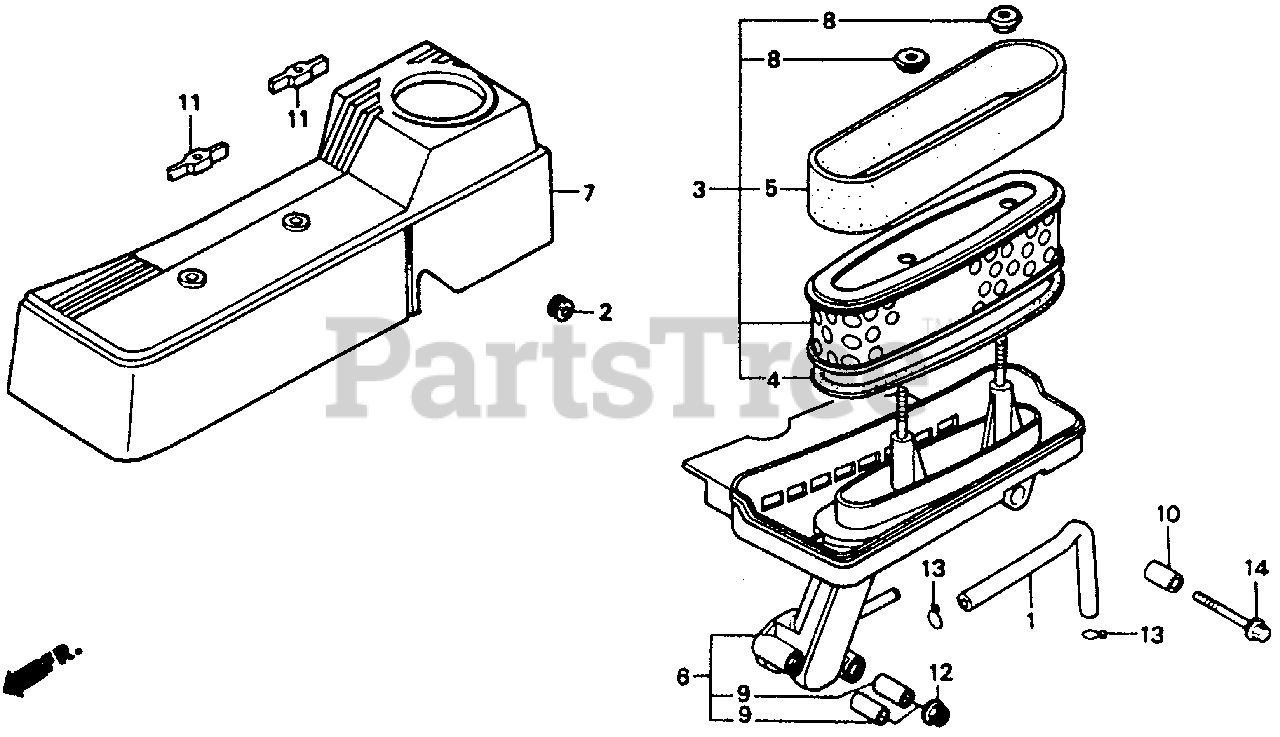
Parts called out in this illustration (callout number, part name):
1	TUBE, BREATHER
2	GROMMET, CHOKE ROD
3	ELEMENT, AIR CLEANER
4	GASKET, ELEMENT
5	FILTER (OUTER)
6	HOUSING, AIR CLEANER
7	COVER, AIR CLEANER
8	GROMMET, AIR CLEANER
9	COLLAR, AIR CLEANER Use from Engine SN 1786085.
9	COLLAR, AIR CLEANER
10	COLLAR B, AIR CLEANER
11	WINGNUT (6MM)
12	NUT, FLANGE (6MM)
13	CLIP, TUBE (B12) Use from Engine SN 2086984.
14	BOLT, FLANGE (6X35)
